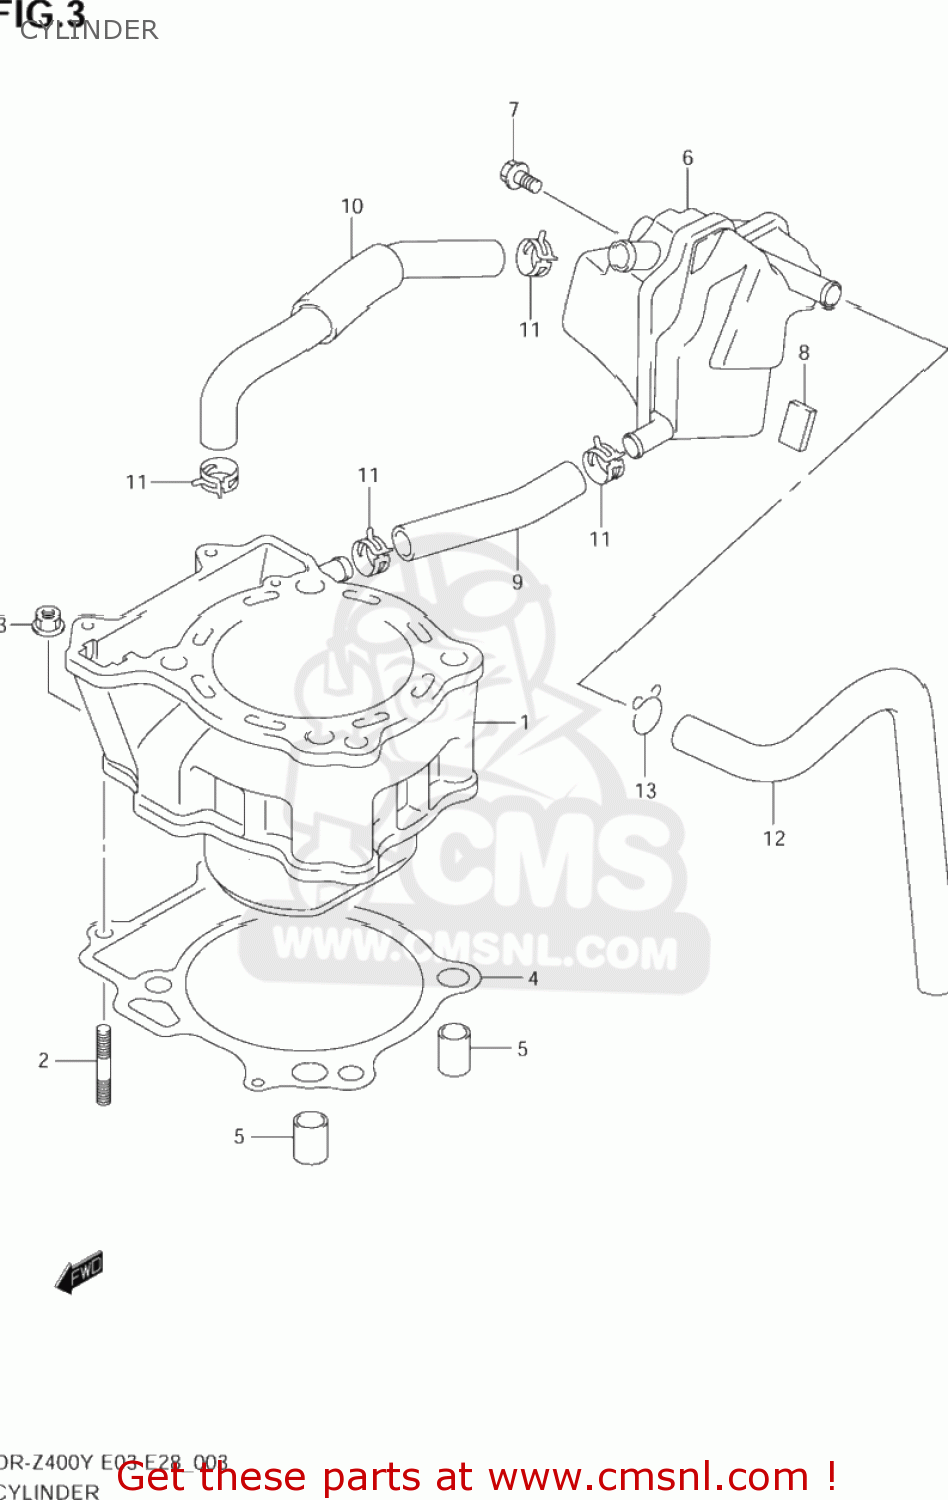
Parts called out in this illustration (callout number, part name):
1	CYLINDER
2	STUD BOLT
3	NUT
4	GASKET,CYLINDER (NAS)
5	PIN
6	TANK,OIL RETURN
7	BOLT
8	PROTECTOR(170X95X3.0)
9	HOSE,BREATHER
10	HOSE,BREATHER
11	CLIP
12	HOSE,BREATHER
13	CLIP
